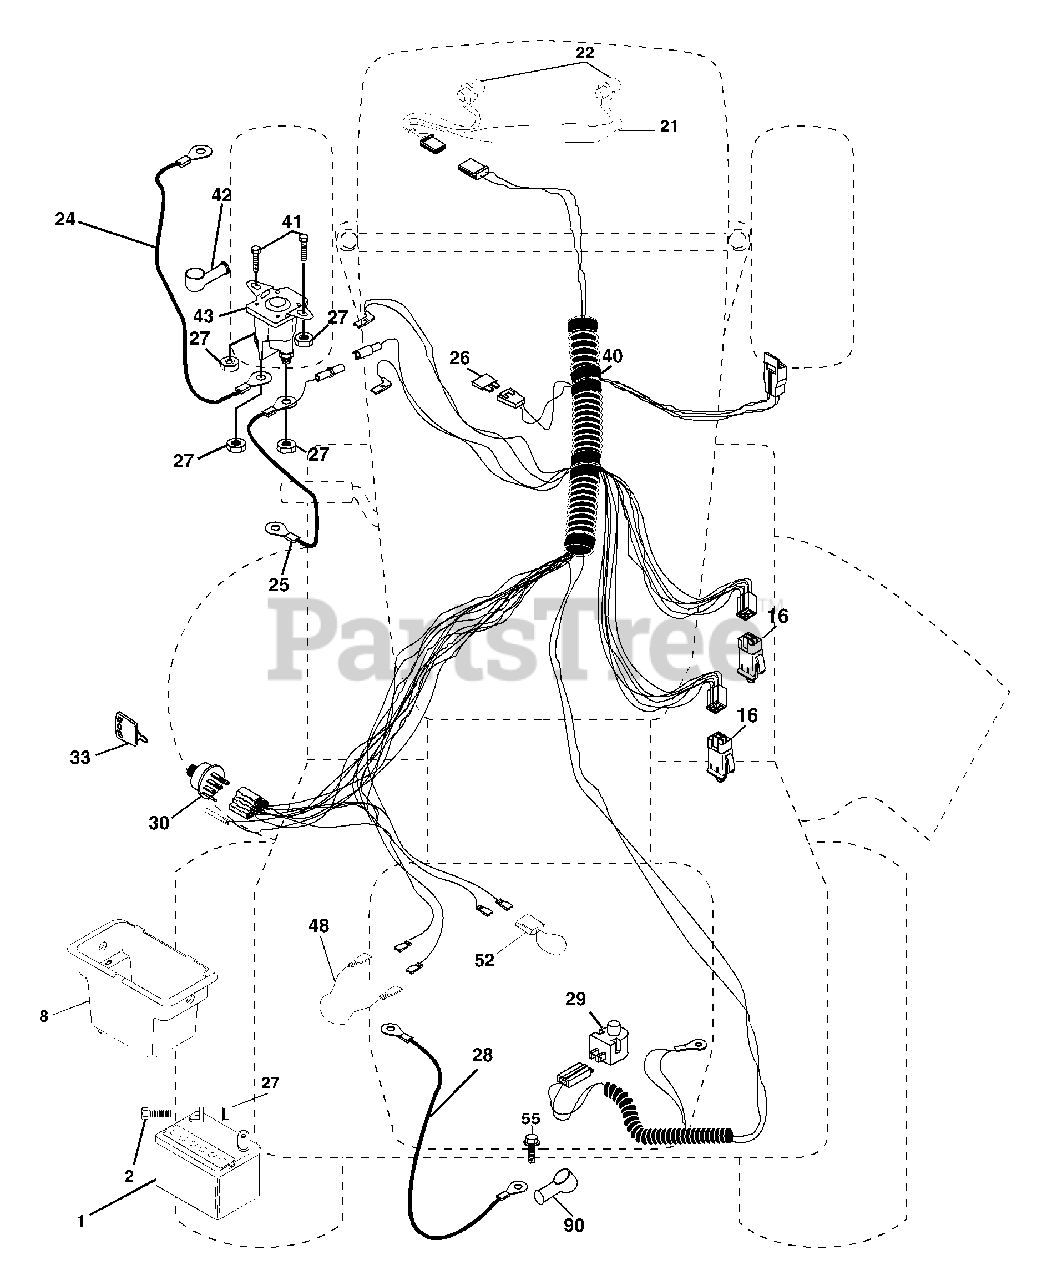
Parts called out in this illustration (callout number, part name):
1	Battery
2	Bolt Hex Hd 1/4-20unc X 3/4
8	Battery Box
16	Switch Interlock Push-In
21	Harness Socket Light
22	Bulb, Light # 1156
24	Cable Battery
25	Cable Battery 6 Ga Red w/16 wire
26	Fuse
27	Nut Keps Hex 1/4-20 Unc
28	Cable Ground 6ga 12 black
29	Switch Plunger Nc Gray
30	Switch Ign
33	Key Ign Molded Generic
40	Harness Ign
41	Bolt Fin Hex 1/4-20 unc x 1/2
42	Cover Terminal Red
43	Solenoid
48	Adapter Ammeter
52	Protection Loop
90	Cover Terminal
